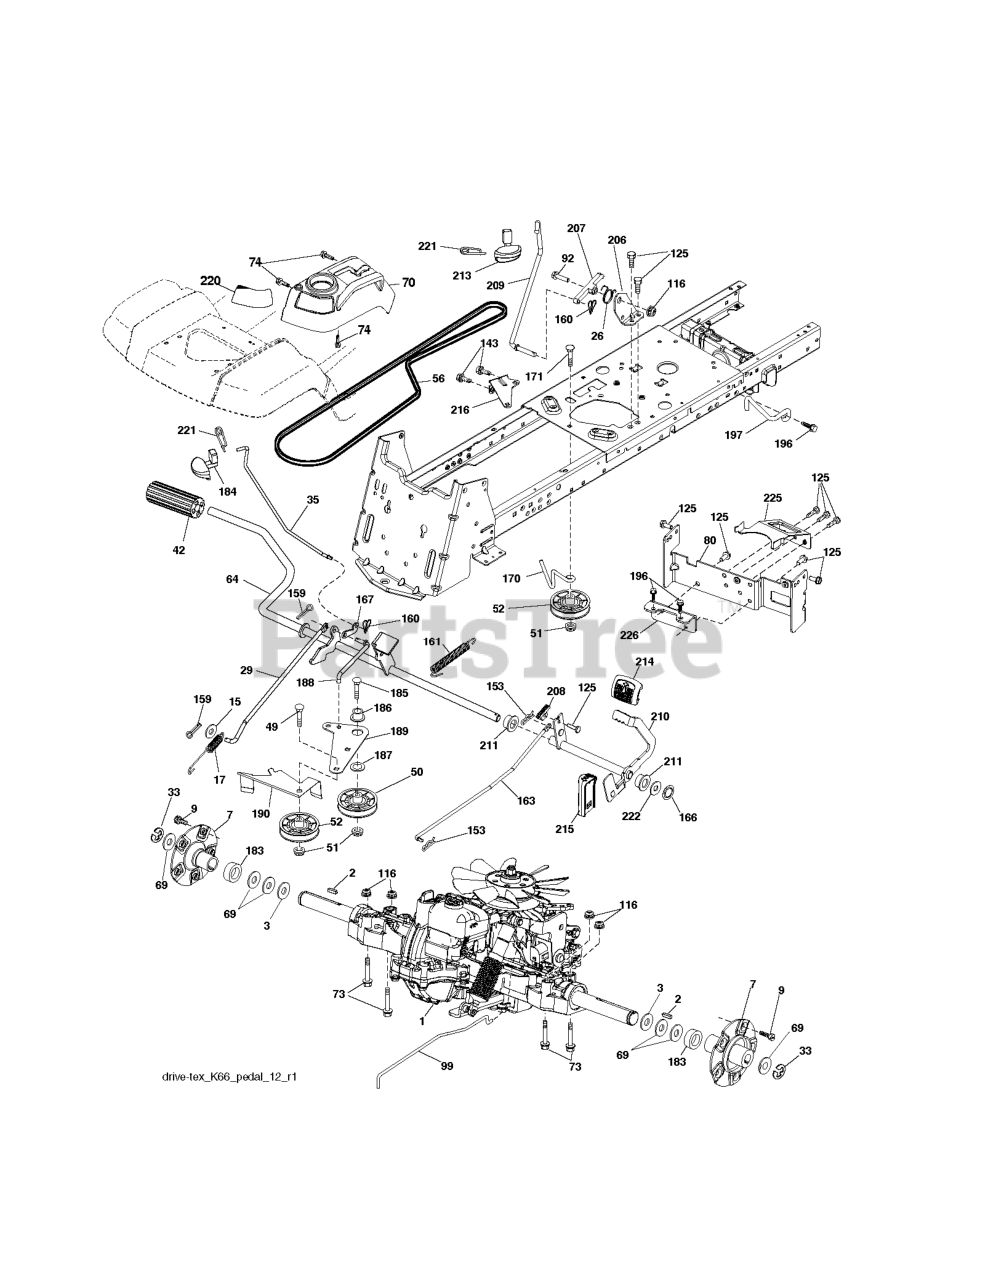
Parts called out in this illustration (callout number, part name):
2	KEY 1/4 X 2.5
7	HUB.ASM.WHEEL.REAR.23"TEX
15	WASHER
17	SPRING.BRAKE.K46
26	SPRING.RETURN.CRUISE
29	ROD.BRAKE.K66
33	E RING HYT
35	ROD .BRAKE. PARKING. GT. HUSQ.
42	PEDAL COVER T
50	IDLER.FLAT.910.OFFSET
51	NUT LOCK FLG 3/8-16 UNC
52	IDLER.V-GROOVE.910.OFFSET
64	SHAFT.ASM.PEDAL.BRK.CNTR
70	CONSOLE.ASM.RH.GT.FC.HUSQ
73	BOLT HEX 5/16-18 GR 5
74	SCREW.HI-LO.CONSOLE
80	STRAP.TORQUE.K66
92	BOLT
99	ROD.SPRING.BYPASS.K66.GT.Z
116	NUT LOCK HEX FLANGE 5/16-18
125	SCREW
143	Screw 5/16-18 x 1/2 Hex, Self Tapping 5/16-18 x 1/2
153	RETAINER M
159	COTTER PIN
160	RETAINER CLIP
161	SPRING, RETURN LT
163	ROD.PEDAL.CONTROL
166	NUT.PUSH.625
167	LATCH.BRAKE.SPRING
170	KEEPER.V-IDLER.CENTER.
183	SPACER.AXLE.HG.TEX
184	HANDLE.PARKG.BRK.HUSQ X667
186	SPACER.RETAINER
187	WASHER 12/32X2X10GA
188	RP.LINK.CLUTCH.GROUND.DRIVE
189	BELLCRANK.GROUND.DRIVE.TEX.
190	KEEPER.BELLCRANK.DRIVE
196	SCREW 3/8-16X1
197	BRKT.ANIT-ROTATION.CLUTCH
206	BRKT.MOUNT.LATCH.CRUIS
207	LATCH.CONTROL.CRUISE
208	GEAR.SECTOR.CONTROL.CR
209	ROD.CONTROL.CRUISE.GT.
210	ROCKER.ASM.PEDAL.CONTR
211	BEARING.NYLON
213	KNOB.CONTROL.CRUSIE.HU
214	PEDAL.FORWARD.PAD.TEX
215	PEDAL.REVERSE.TEX.GT.4
216	BRACKET.PULLEY.IDLER.W/TEX
220	REFLECTOR.RH.TEX GT
221	RETAINER.SPRING.CLIP.H
222	WASHER 21/32 X 1-1/4 X 10 GA.
225	KEEPER.BELT.TRANSAXLE.K66
226	BRACKET.MOUNT.TORQUE.K66.TG
